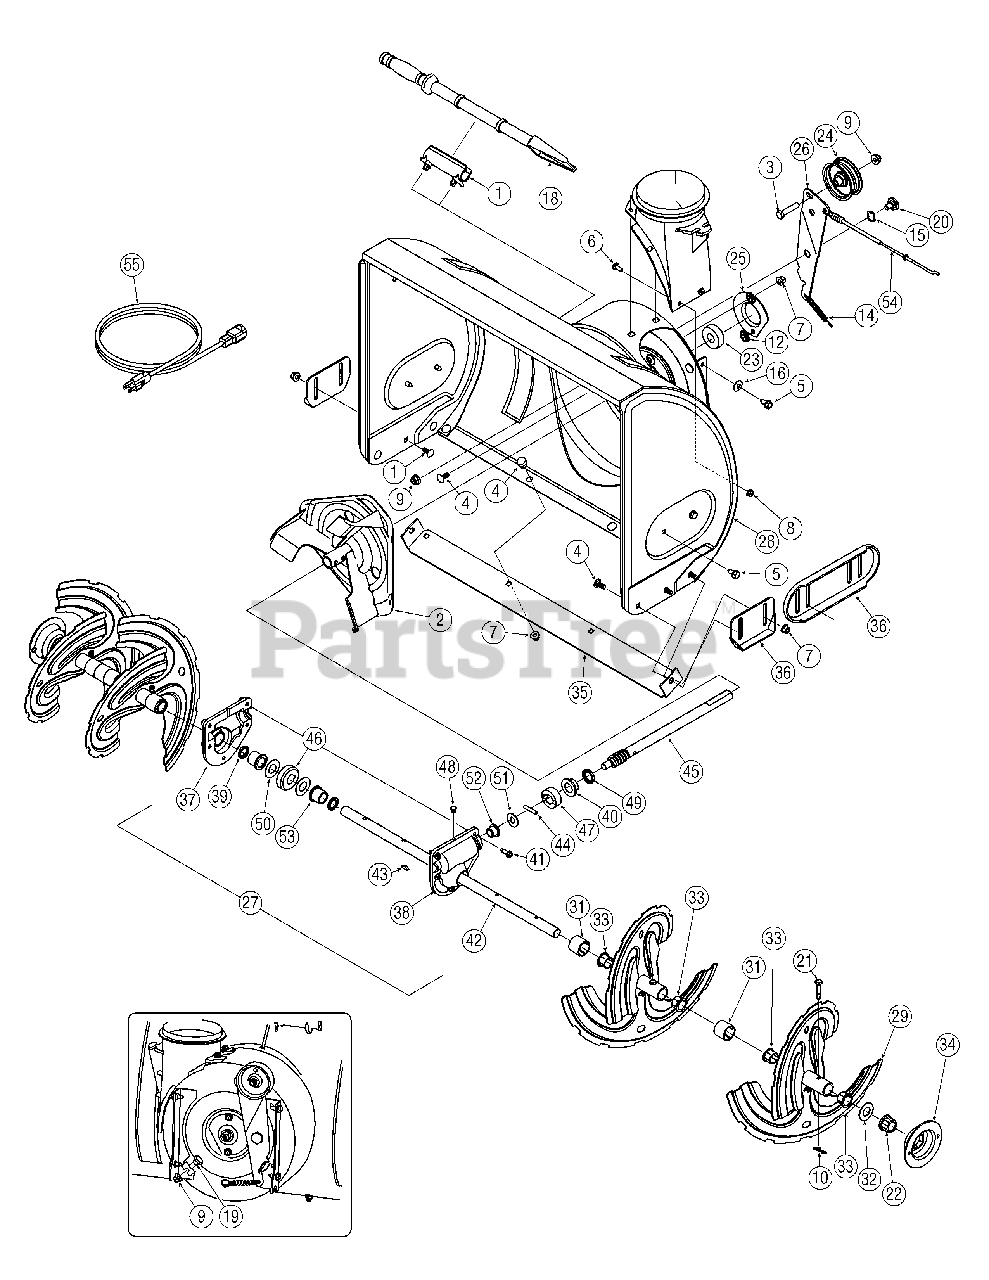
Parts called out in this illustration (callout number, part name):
1	Snow Removal Tool Mount
3	Hex Screw, 3/8-16, 1.75, Gr5
4	Bolt, Carriage, 5/16-18, .750 Gr1
5	Screw, 5/16-18, 0.625
6	Screw, Carriage, 1/4-20, .750, Gr5
7	Nut, Flange Lock, 5/16-18, Nylon
8	Nut, Flange Lock, 1/4-20, Nylon
9	Nut, Flange Lock, 3/8-16, Nylon
10	Cotter Pin, Bow-tie
11	Cable, Tie, 3/16 x .05 x 7.4
12	Nut, Push-on, .25 Dia
13	Chute, Adapter 5" Dia
14	Spring, Extension, .38 OD x 3.6
15	Washer, Wave, .625 x .885 x.015
16	Washer, Bell, .340 x .872 x .060
17	Washer, Flat, .25 x .630 x .0515
18	Snow Removal Tool
19	Screw, Shoulder, .498 x .34, 3/8-16
20	Screw, Shoulder, .625 x .17, 3/8-16
21	Shear Pin, .25 x 1.50
22	Bearing, Hex Flange x .75 ID
23	Bearing, Ball, .75 ID x 1.85 OD
24	Flat Pulley, Idler, 2.75 OD
25	Housing, Bearing, 1.85 ID
27	Gearbox Assembly, Auger, 22"
27	Gearbox Assembly, Auger, 24"
27	Gearbox Assembly, Auger, 26"
27	Gearbox Assembly, Auger, 28"
31	Spacer, 1.25 OD x .75 ID
32	Washer, Flat, .76 x 1.49 x .06
33	Bushing, Flange, .80 ID x .91 OD
37	Housing, Auger, RH Reduced
38	Housing, Auger, LH Reduced
39	Seal, Oil, .750 ID
40	Bearing, Flange, .75 x 1.0
41	Screw, Self-tapping, 1/4-20, 0.750
42	Axle, Auger, 22"
42	Axle, Auger, 24"
42	Axle, Auger, 26"
42	Axle, Auger, 28"
43	Key, Hi-pro 3/16 x 5/8
44	Pin, Dowel, .25 OD x 1.2
45	Shaft, Worm .75 OD
46	Gear, Worm 20T
47	Collar, Thrust
48	Plug, 1/4 x .437
49	Seal, Oil, .75 x 1 x .131
50	Washer, Flat, .760 ID x 1.5 OD
51	Washer, Flat, .51 x 1.12
52	Bearing, Flange, .75 x 1.0 x .925
53	Bearing, Flange, .75 x 1.00 x .975
54	Clutch Cable, Auger, 47.23"
55	Extention Cord, 110V
